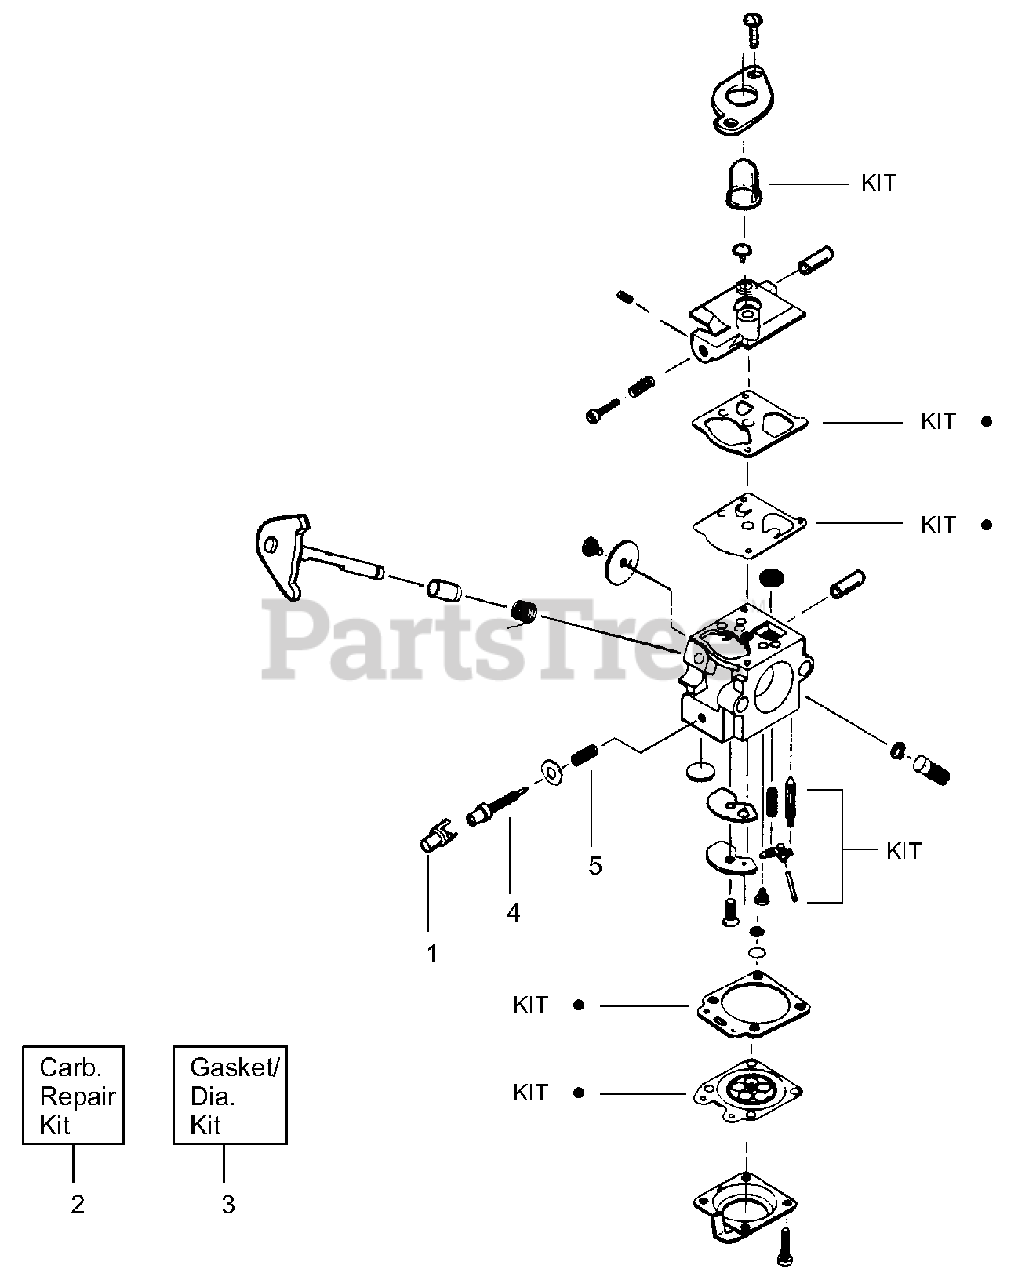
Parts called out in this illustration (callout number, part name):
1	Limiter Cap
2	Carburetor Repair Kit
3	Gasket Diaphragm Kit
4	Needle-Idle
5	Spring-Idle Needle
